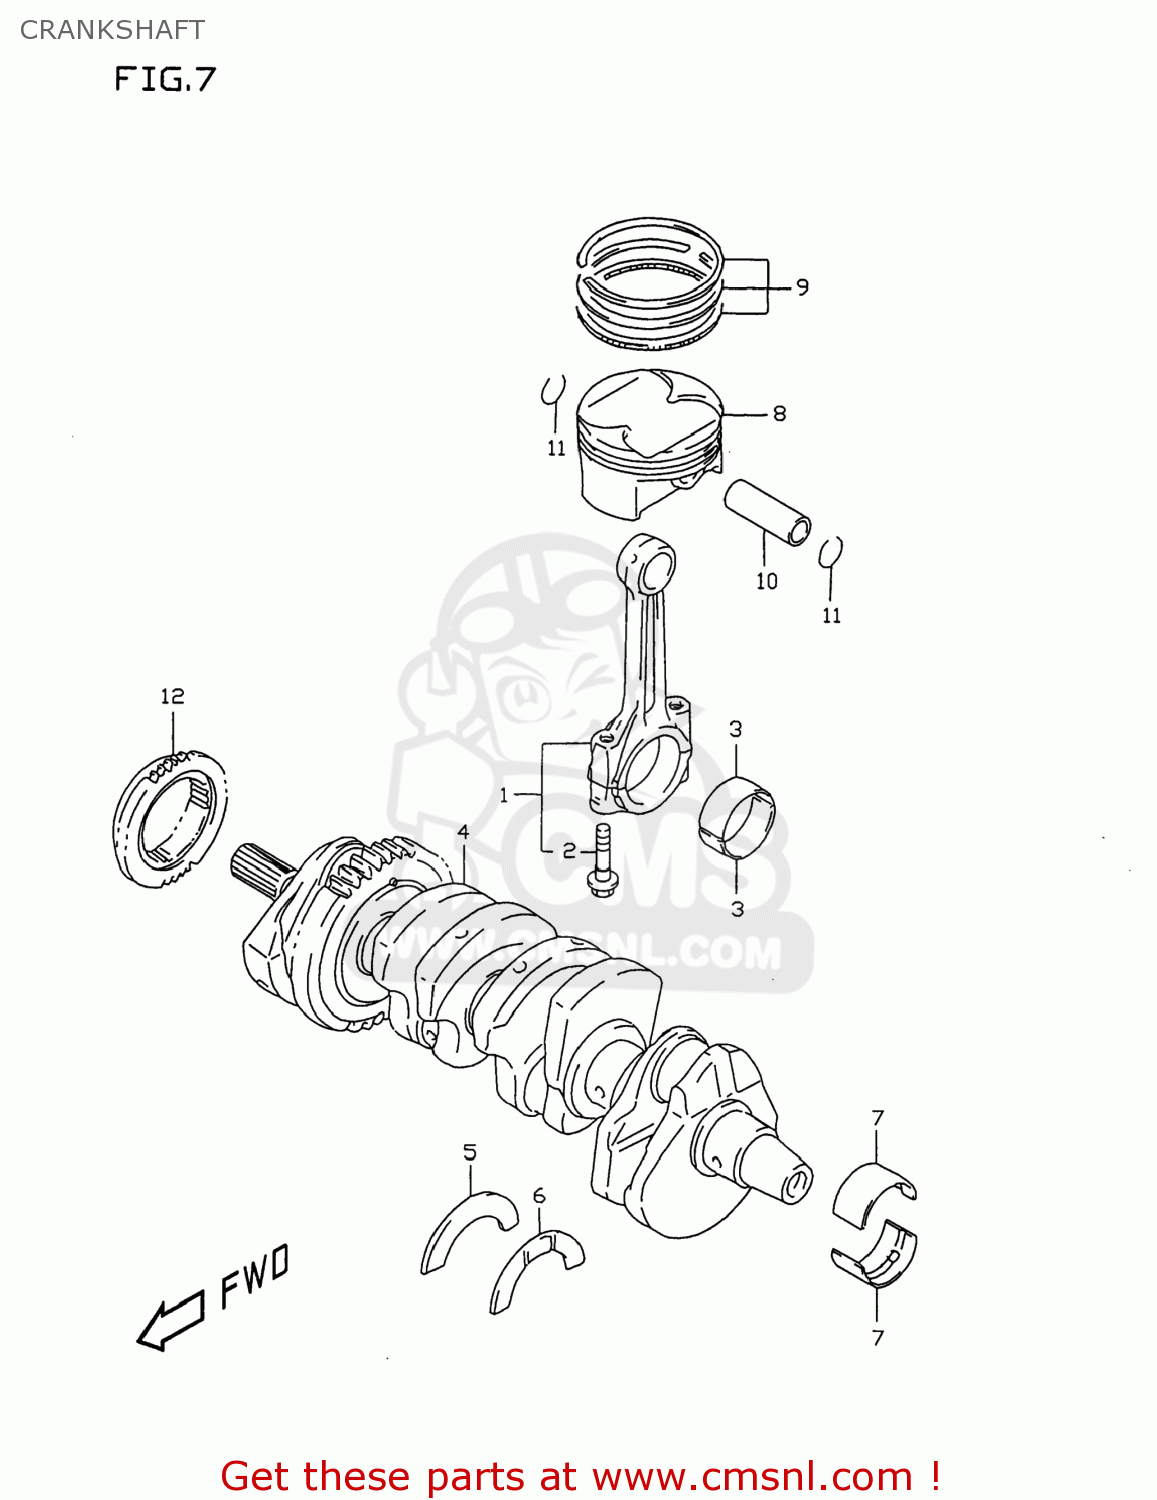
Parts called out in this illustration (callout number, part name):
1	CONNECTING ROD ASSEMBLY
2	BOLT,CONNECTING ROD
3	BEARING,CRANK PIN
4	CRANKSHAFT SET
5	BEARING,CRANK THRUST(GREEN)
6	BEARING,CRANK THRUST(RED)
7	BEARING,CRANKSHAFT(GREEN)
8	PISTON
9	RING SET,PISTON
10	PIN,PISTON
11	CIRCLIP
12	SPROCKET,CAM CHAIN DRIVE
